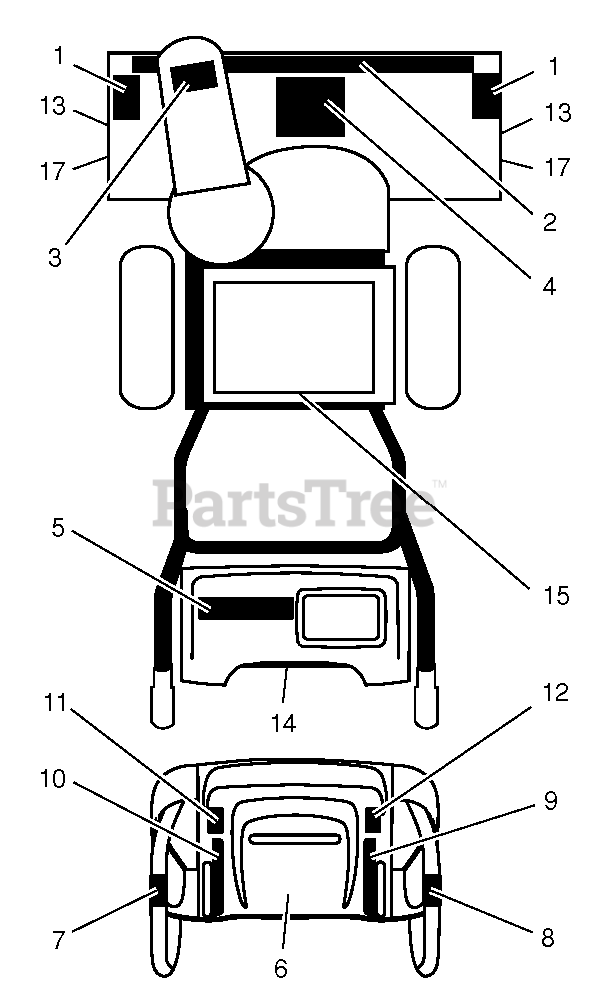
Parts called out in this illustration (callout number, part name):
1	DECAL.AUGER.SAFETY.
3	DECAL.CHUTE.SAFETY.
4	DECAL.AUGER."
6	DECAL.CONSOLE.INSTRUCTION
10	DECAL.REM.DEFLECTOR.LT
11	DECAL, LH TRIGGER
12	DECAL, RH TRIGGER
14	DECAL.FENDER
15	DECAL.BELT.GUARD.
17	DECAL, HUSQVARNA
